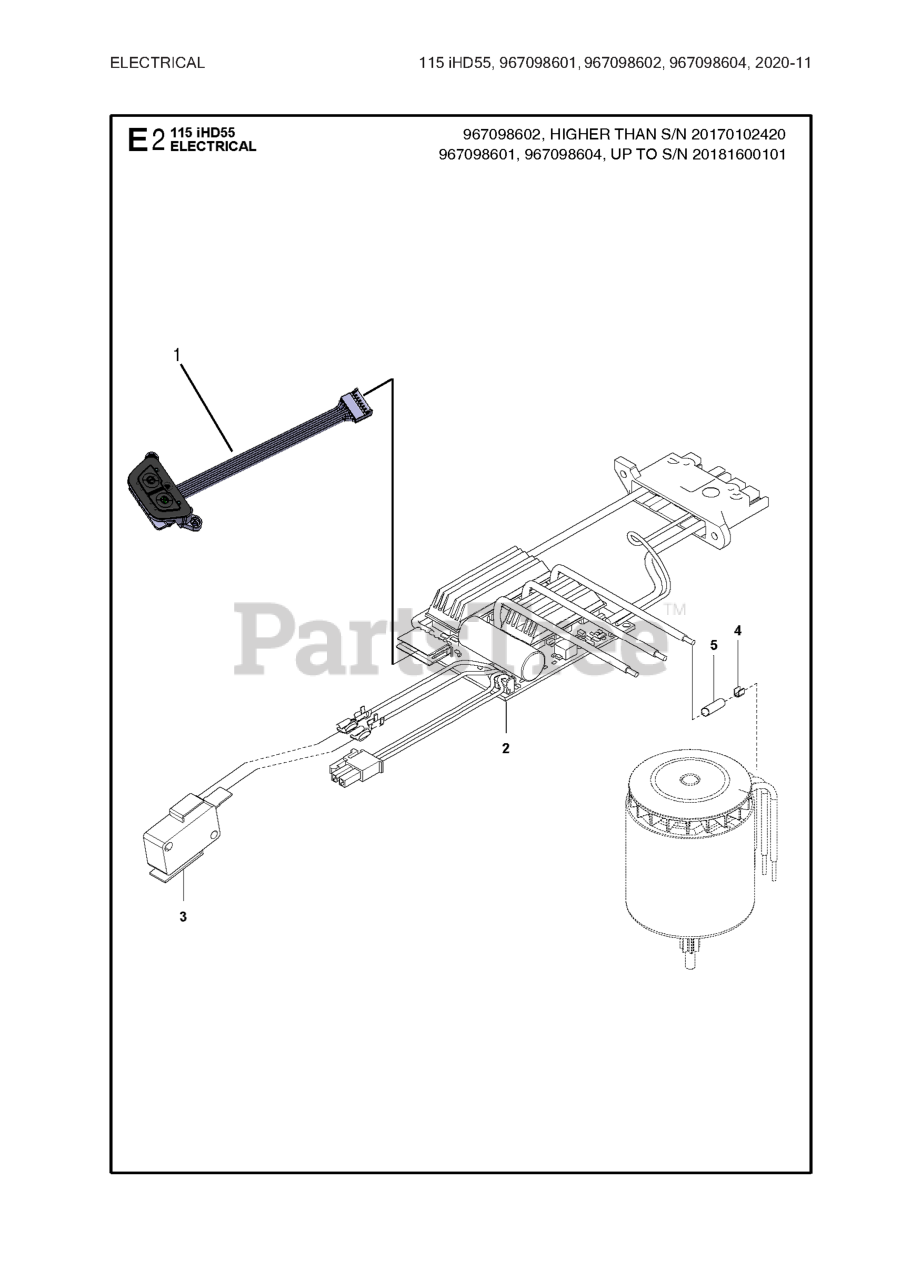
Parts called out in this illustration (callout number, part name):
1	KEYPAD ASSEMBLY
2	CONTROL UNIT CONTROL UNIT BLDC
3	MICRO SWITCH
